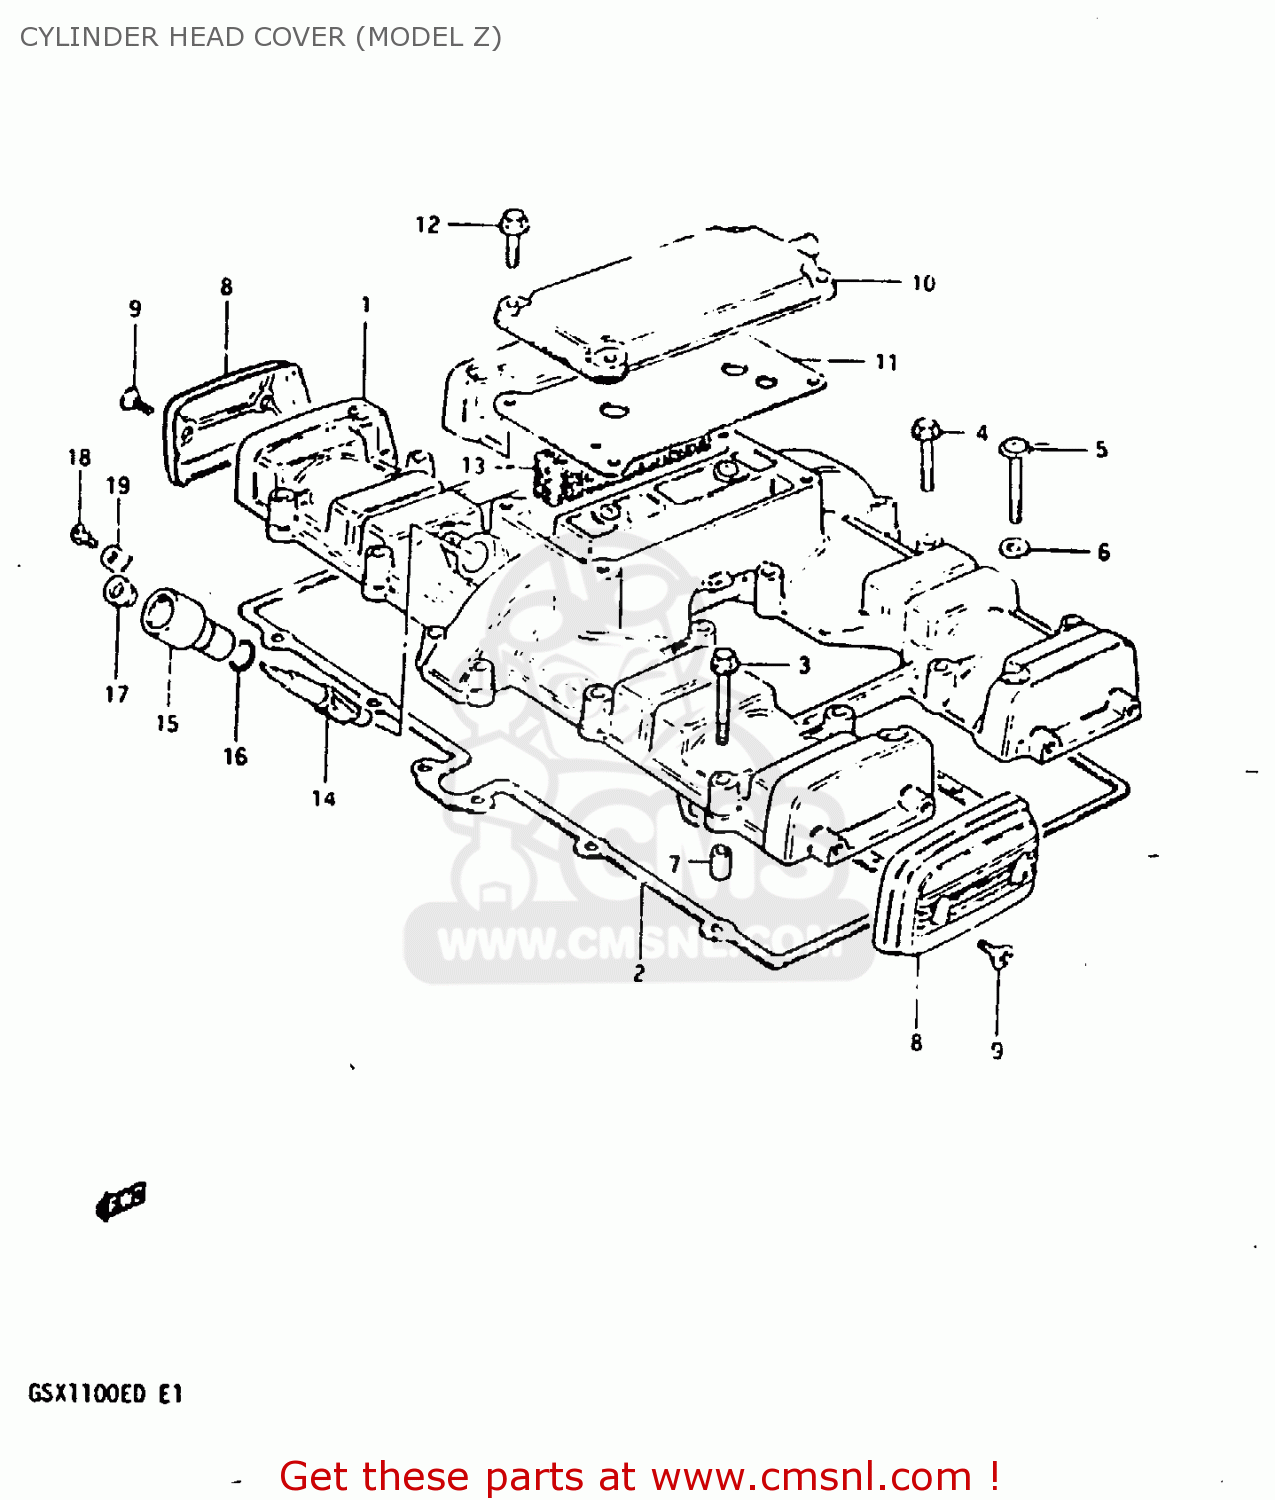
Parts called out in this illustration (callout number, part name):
1	COVER,CYLINDER HEAD
2	GASKET,CYLINDER HEAD COVER (MCA)
3	BOLT
4	BOLT 6X35
5	SCREW 6X40
6	GASKET (NAS)
7	PIN(6.2X8X11)
8	CAP,CYLINDER HEAD COVER
9	SCREW(5X12)
10	COVER,BREATHER
11	GASKET (MCA)
12	BOLT,REAR
13	COVER,BREATHER
14	GEAR,TACHOMETER DRIVEN
15	SLEEVE,TACHOMETER DRIVE
16	SEAL,TACHOMETER DRIVEN
17	SEAL,OIL(5X12X8)
18	SCREW(5X12)
19	PLATE,TACH DRIVE GEAR SLEEVE
